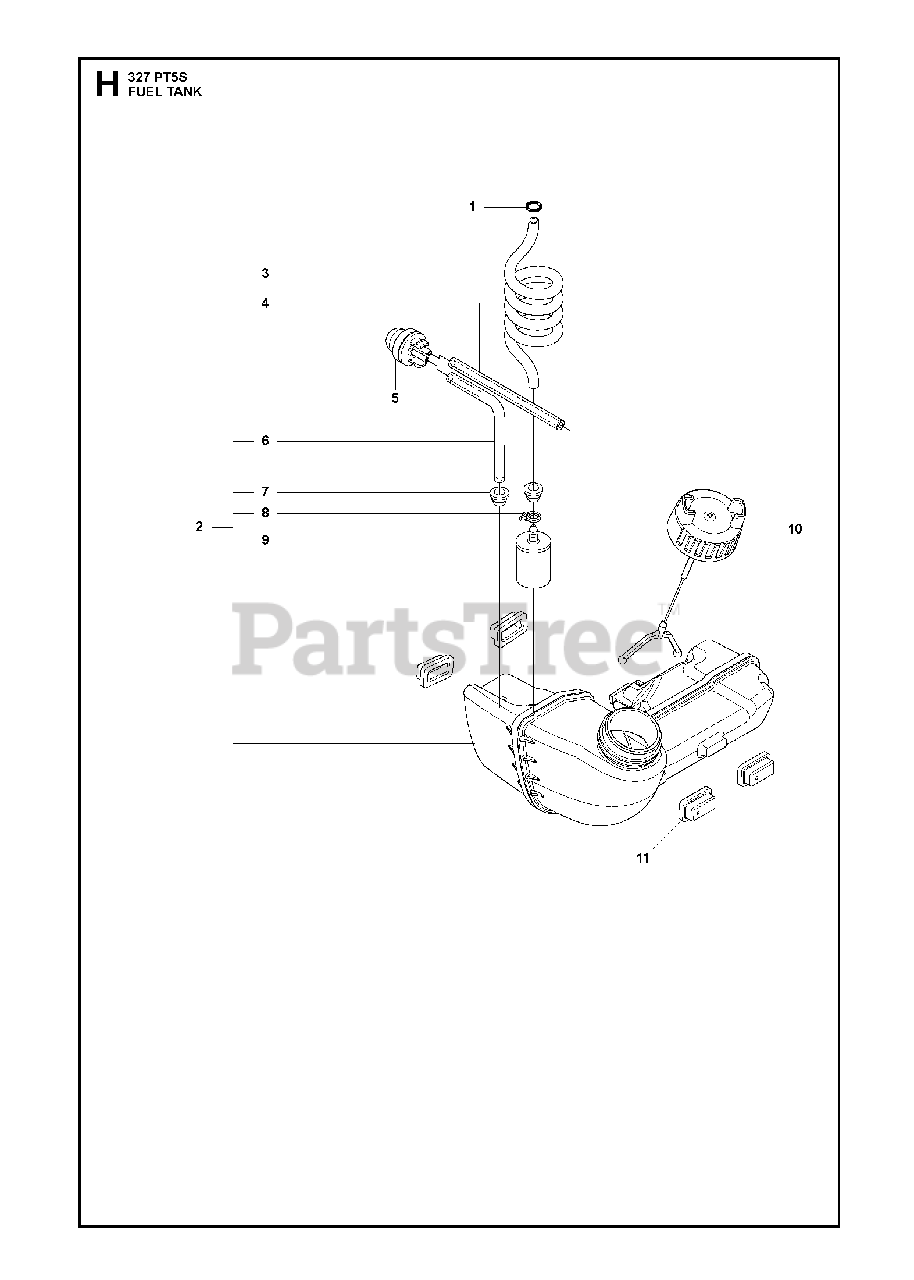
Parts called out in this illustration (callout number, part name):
2	RP FUEL TANK ASSY
3	FUEL HOSE
4	HOSE
5	AIR PURGE BUBBLE
6	HOSE
7	FUEL TANK BUSHING
8	HOSE CLAMP
9	FUEL FILTER
10	%FUEL CAP
